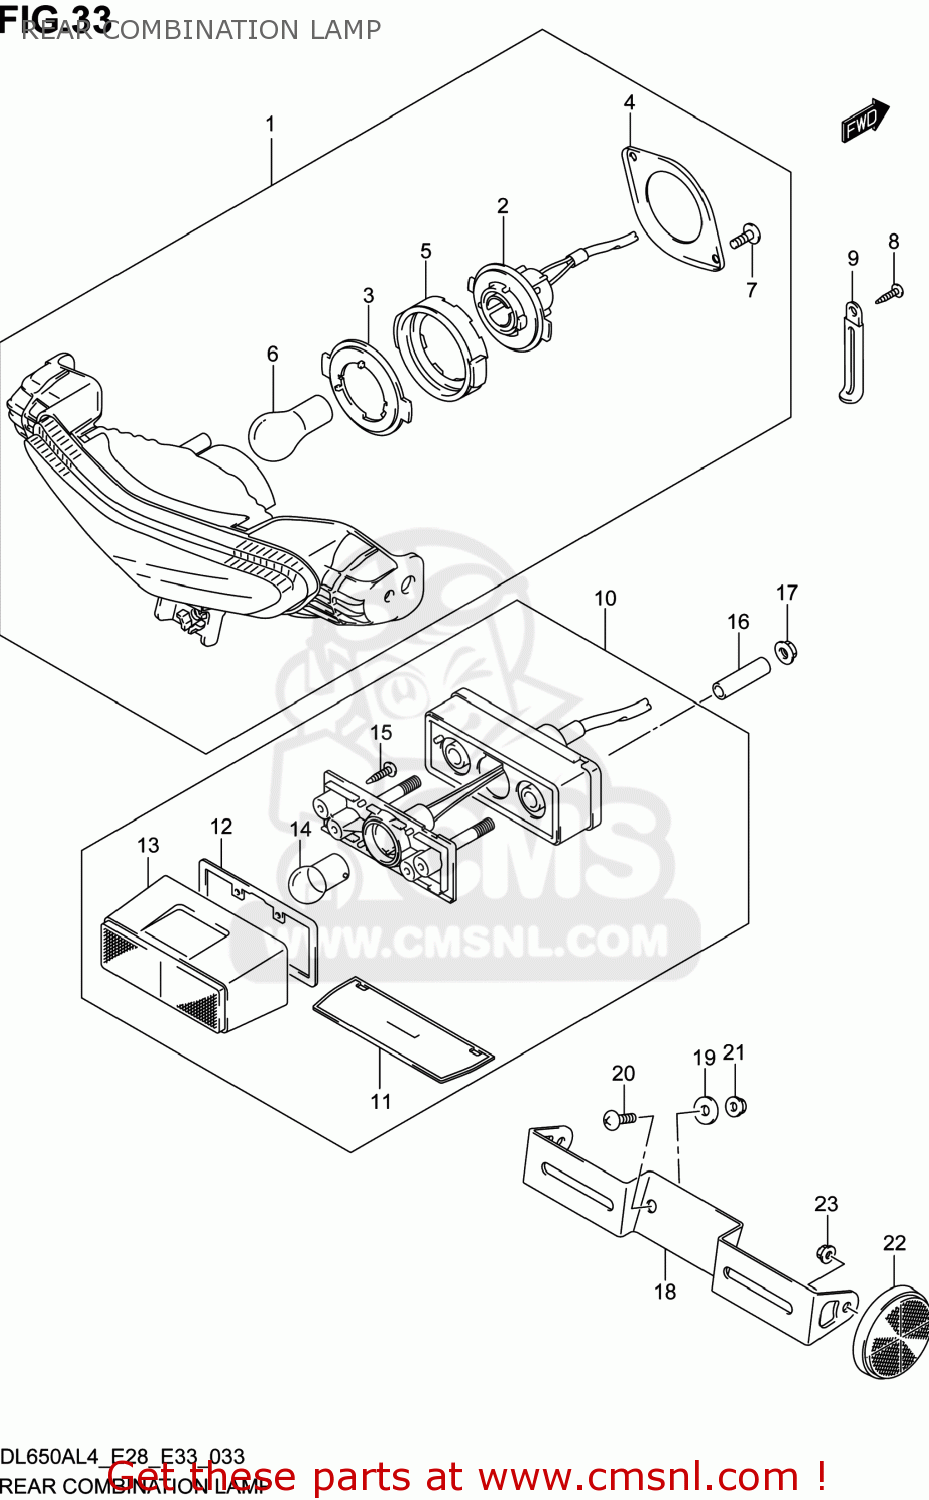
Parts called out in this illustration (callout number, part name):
1	LAMP ASSY,RR COMBINATION
2	SOCKET & CORD
3	PLATE NO.1
4	PLATE NO.2
5	CUSHION
6	BULB(12V21/5W)
7	SCREW
8	SCREW
9	CLAMP(L:45)
10	LAMP ASSY,LICENSE
11	LENS,LICENSE LAMP
12	GASKET (NAS)
13	COVER,LICENSE LAMP
14	BULB(12V5W,BF150-40160A)
15	SCREW
16	SPACER(6.5X9X33.3)
17	NUT
18	BRACKET,LICENSE PLATE
19	WASHER(6.5X20X1.2)
20	SCREW
21	NUT
22	REFLECTOR ASSY,RR SIDE
23	NUT
